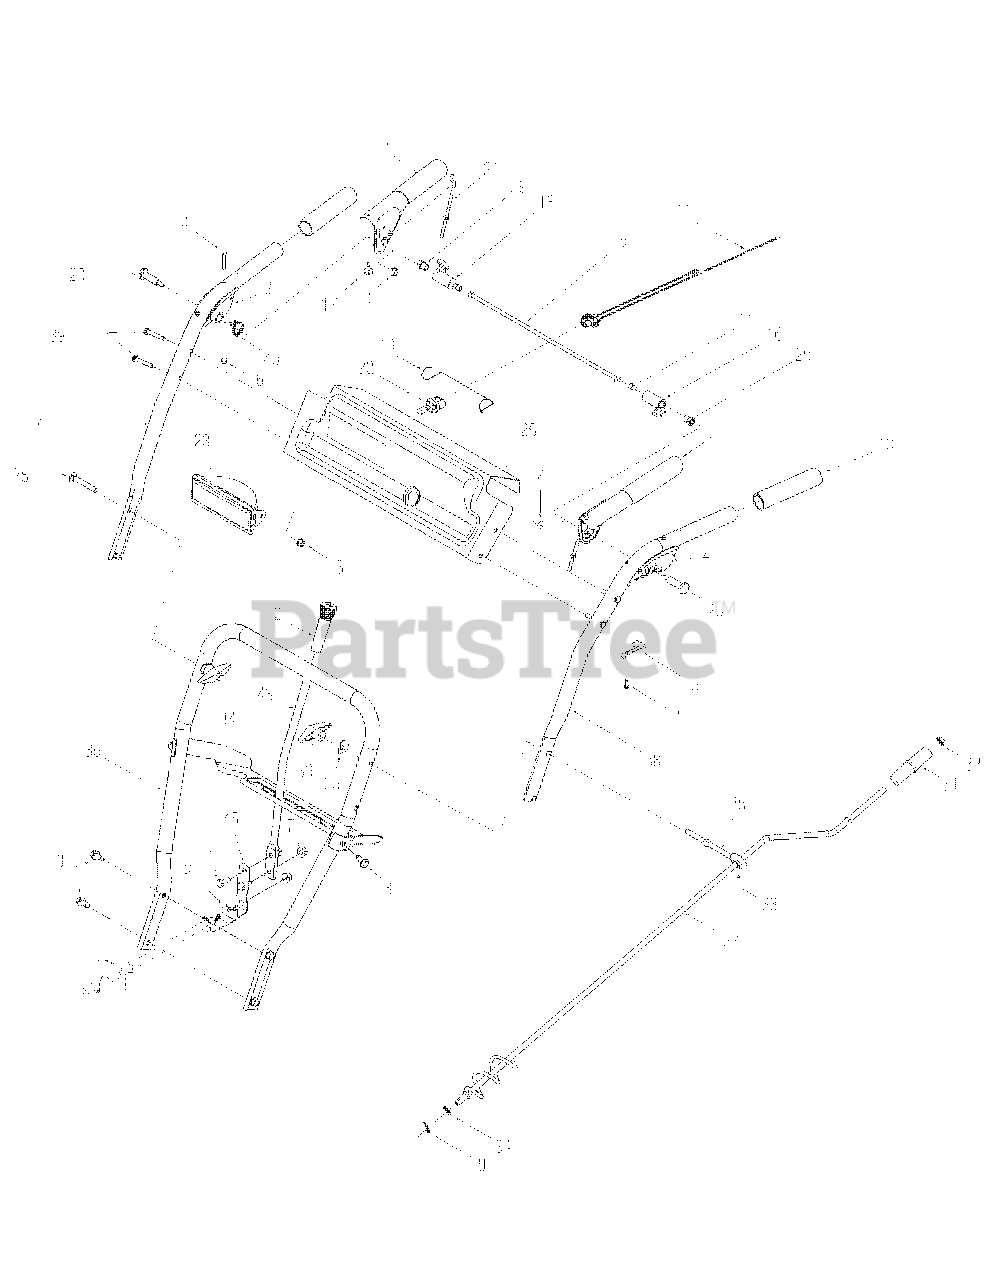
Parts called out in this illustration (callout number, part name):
1	Handle Ass'y, Engagement RH Black
2	Handle Ass'y, Engagement, LH Black
3	Screw, Self-tapping, 5/16-12, 0.750
4	Screw, Machine, #10-24, 1.375
5	Screw, #8-18 x .375
6	Nut, Hex Lock, #10-24, Gr2, Nylon
7	Nut, Flange Lock, 5/16-18, Grf, Nylon
8	Nut, Flange Lock, 1/4-20, Grf, Nylon
9	Pin, Cotter, .072 x 1.13
10	Grip, 1.0 ID x 5.0
11	Screw, 1/4-20, .375
12	Rod, Pivot
13	Handle, Clutch Lock, RH
14	Handle, Clutch Lock, LH
15	Spring, Control Lever Lock
16	Cam, Lock
17	Bumper, Rubber, .62 OD x .22
18	Plate, Lock
19	Retainer, Lens
20	Screw, Shoulder, .437 x 1.345, 1/4-20
21	Z Fitting, Cable
22	Lamp, Halogen, 12V, 27W
23	Lens Assembly, Lamp
24	Harness, Headlight
25	Eye Bolt, Chute Crank
28	Screw, Carriage, 5/16-18, 2.25, Gr5
29	Shoulder Nut, Hex, 1/4-20
30	Knob Assembly, Wing Nut, 5/16-18
31	Crank Knob, 1.0 Diameter x 3.2, Black
32	Cap, Push, 3/8 Rod
33	Grommet, .44 ID x .94 OD x .50
34	Washer, Flat, .375 x .738 x .063
35	Washer, Saddle, 320 x .93 x .060
39	Screw, Hex, 1/4-20 x 1.5
40	Spring, Torsion, .8156 x .3038
41	Screw, 5/16-18 x 1.0
44	Panel, Speed Selector (5 FW, 2 RV)
45	Spring, Shift Lever
46	Bracket, Shift Spacer
